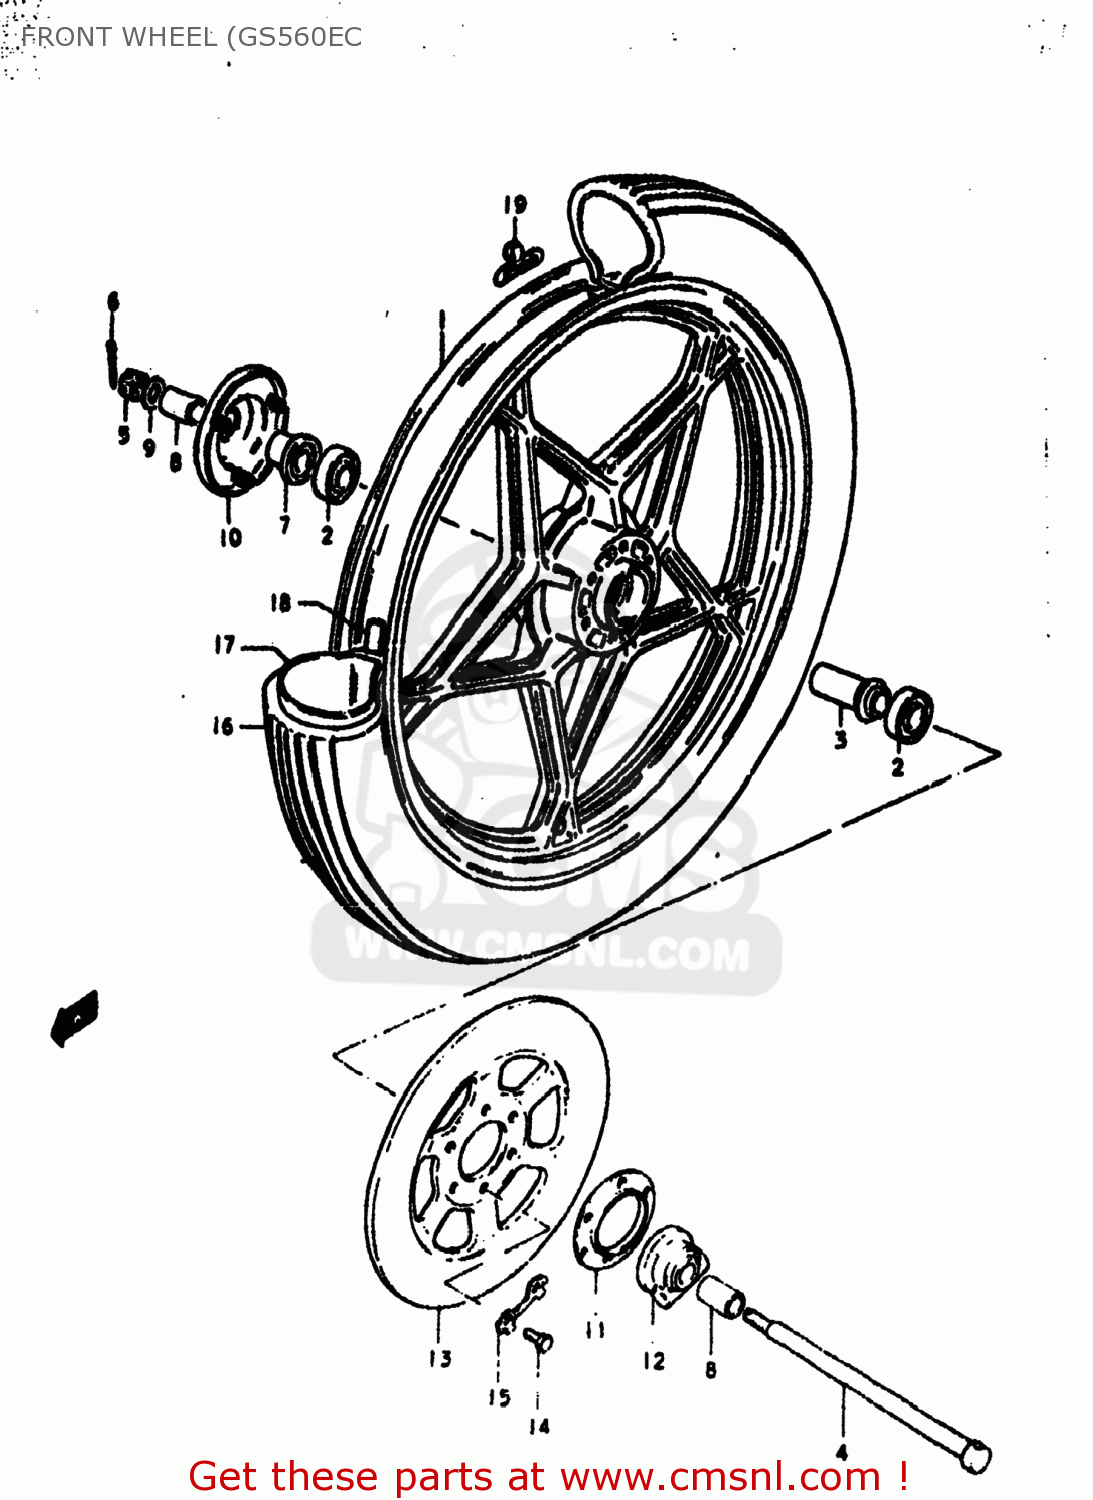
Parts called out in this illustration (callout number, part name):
1	WHEEL, FRONT
2	BEARING
3	SPACER,FR HUB BEARING
4	AXLE,FRONT
5	NUT 12MM
6	COTTER PIN
7	SPACER,FR AXLE,R
8	SPACER(15X22X30)
9	WASHER
10	COVER,FR HUB,R
11	DUST SEAL,SPEEDOMETER GEAR BOX
12	BOX ASSEMBLY,SPEEDOMETER GEAR
13	DISC,BRAKE
14	BOLT(8X25)
15	WASHER
16	TIRE,FRONT
17	TUBE,INNER
18	PROTECTOR,WHL INR TUBE
19	BALANCER,WHEEL
